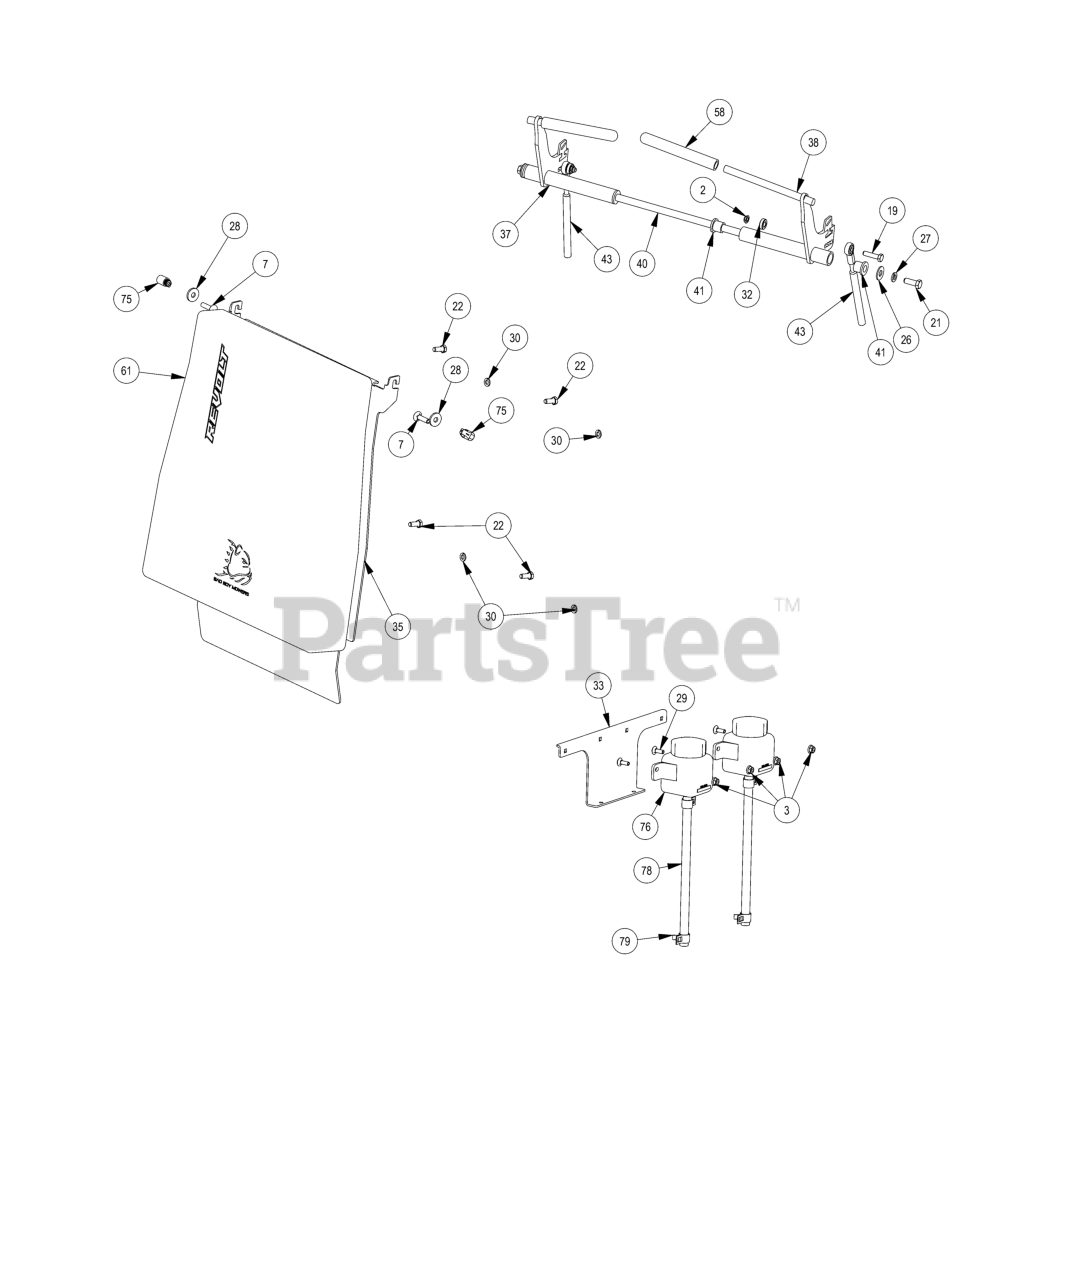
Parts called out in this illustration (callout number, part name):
1	5/16-18 HEX SERRATED FLANGE NUT HARD/ZINC
2	5/16-18 Nylock Jam Nut
3	1/4-20 NYL INSERT FLANGE LOCKNUT ZINC
4	3/8 Nylock Flange Nut
5	5/16-18 NYLON INSERT FLANGE LOCKNUT ZINC
6	10-24 NYLON INSERT LOCKNUT ZINC
7	5/16-18 X 1-1/4 CARRIAGE BOLT ZINC
8	3/8-16 x 1-1/4 Carriage Bolt
9	10-24 X 5/8 BUTTON SOCKET CAP SCREW 18-8 STAINLESS STEEL
11	Tank Strap
12	2019 REVOLT FUEL TANK
13	5/16-18 X 6 CARRIAGE BOLT (GR.5) ZINC
14	8-32 HEX M/S NUT ZINC
15	3/8-24 HEX NUT ZINC YELLOW
16	5/8 Round Insert
17	M6-1.0 X 16MM Hex Bolt
18	12-24 X 1/2 HEX WASHER UNLSOT F TCS ZINC
19	5/16-18 X 1-1/4 HEX C/S (GR.5) ZC
20	5/16-18 X 1-1/2 CARRIAGE BOLT ZINC
21	3/8-16 X 1 GR 5 Hex Bolts Zinc
22	5/16-18 X 3/4 HEX CAP SCREW (GR.5) ZINC
23	5/16-18 X 1 CARRIAGE BOLT (GR.8) ZINC
24	.390 ID X .750 OD X .062 THK FLAT WASHER NYLON
25	.390 ID X 1.12 OD X .125 THK FLAT WASHER NYLON
26	3/8 FLAT WASHER USS (1" OD) ZINC
27	3/8 SPLIT LOCKWASHER ZINC
28	.360 ID X .983 OD X .120 THICK FLAT WASHER NYLON
29	1/4-20 X 3/4 CARRIAGE BOLT (GR.5) ZINC
30	5/16 SPLIT LOCKWASHER ZINC
31	Expandable Locking Grommets
32	ACS Spacer 3/4x3/8x1/4
33	2020 36" Hydrotank Carrier Plate - Raw 2020 36" Stand On
34	2023 Stand on Battery Hold Down
35	2023 36-SD Stand on Pad Plate
36	36" Front Control Arm Stop Weldment - Raw 2020 36" Stand On
37	2023 36-SD Stand On Drive Arm Actuator weldment_left
38	2023 36-SD Stand On Drive Arm Actuator weldment_right
39	2023 36''/SD Control Arm Stop Weldment_Rear
40	2020 36 Stand On Drive Arm Pivot Bar
41	Nylon 6 6 Sleeve Washer
42	Brake Spring
43	2019 Revolt Push Rod Assembly
44	2023 36-SD Stand On Console Bracket Weldment
45	Ignition Key
46	1/4" Vinyl Tubing, 46" Long
47	3/16" Vinyl Tubing, 55" Long
48	Revolt Fuel Line Assembly
50	Universal Throttle Head - 2012
51	Throttle Knob
52	PTO Switch
53	Brake Cable
54	MZ Kohler EPA Canister Assembly
55	Interstate FAYTX14 Battery
56	8507A13 McMaster Carr Plunger
57	2019 Stand On Brake Handle - Raw
58	2019 Stand On Control Grip
59	Rubber Brake Grip-cZT/ZT 2013
60	2019 Stand On Waterbottle Cage
61	SD Seat Pad
62	3/16 Vinyl Clamp
63	3/16" Vinyl Hose Clamp
64	Magnet-Steering Arm-Stand ON
66	Safety Switch
67	Ignition Switch
68	2023 SD Podium Panel Right
69	2023 SD Podium Panel Left
70	36" Podium Front Panel Weldment 2020 Stand On
71	Tachometer
72	Safety Switch Harness
73	36" Control Panel (upper) - Revolt
74	36" Control Panel (lower) - Revolt
75	Adjustable handles ERX.30 B-10-24-C1
76	350ml Expansion Tank
77	Hydraulic Tank Cap
78	ZT/Maverick Hydro Tank Hose
79	3/8" Hose Clamp
80	1/2 Hose Clamp
81	Relay Block Cover Replacement Kit
83	2023 Floor Board Rubber Bumper
84	24" Red Battery Cable
85	Ground Cable
